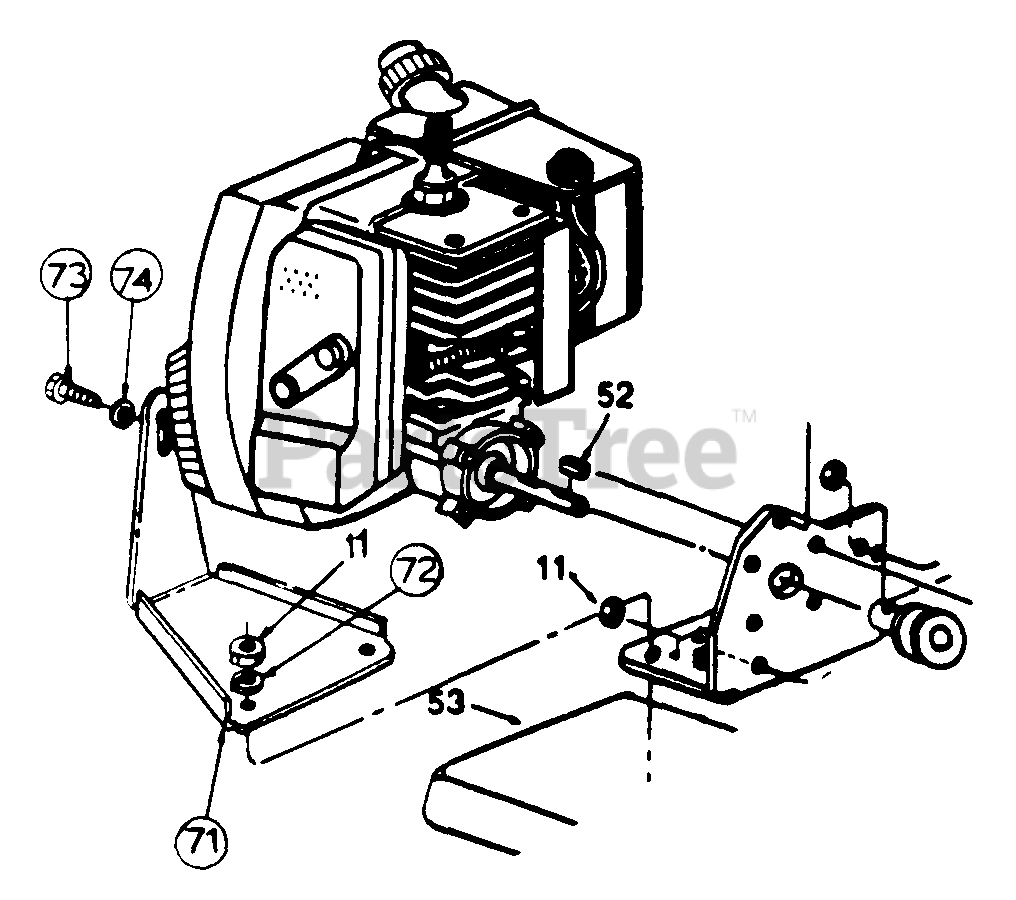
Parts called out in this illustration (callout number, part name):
11	Lock Nut 5/16-18 Thd.
52	Square Key 1/8 x 3/4"
53	Tine Shield (Red)
71	Engine Brace
72	L-Wash. 5/16" I.D.
73	Hex Wash. Hd. F-Tap Scr. #10-24 x .5" Lg.
74	L-Wash. #10 I.D.
